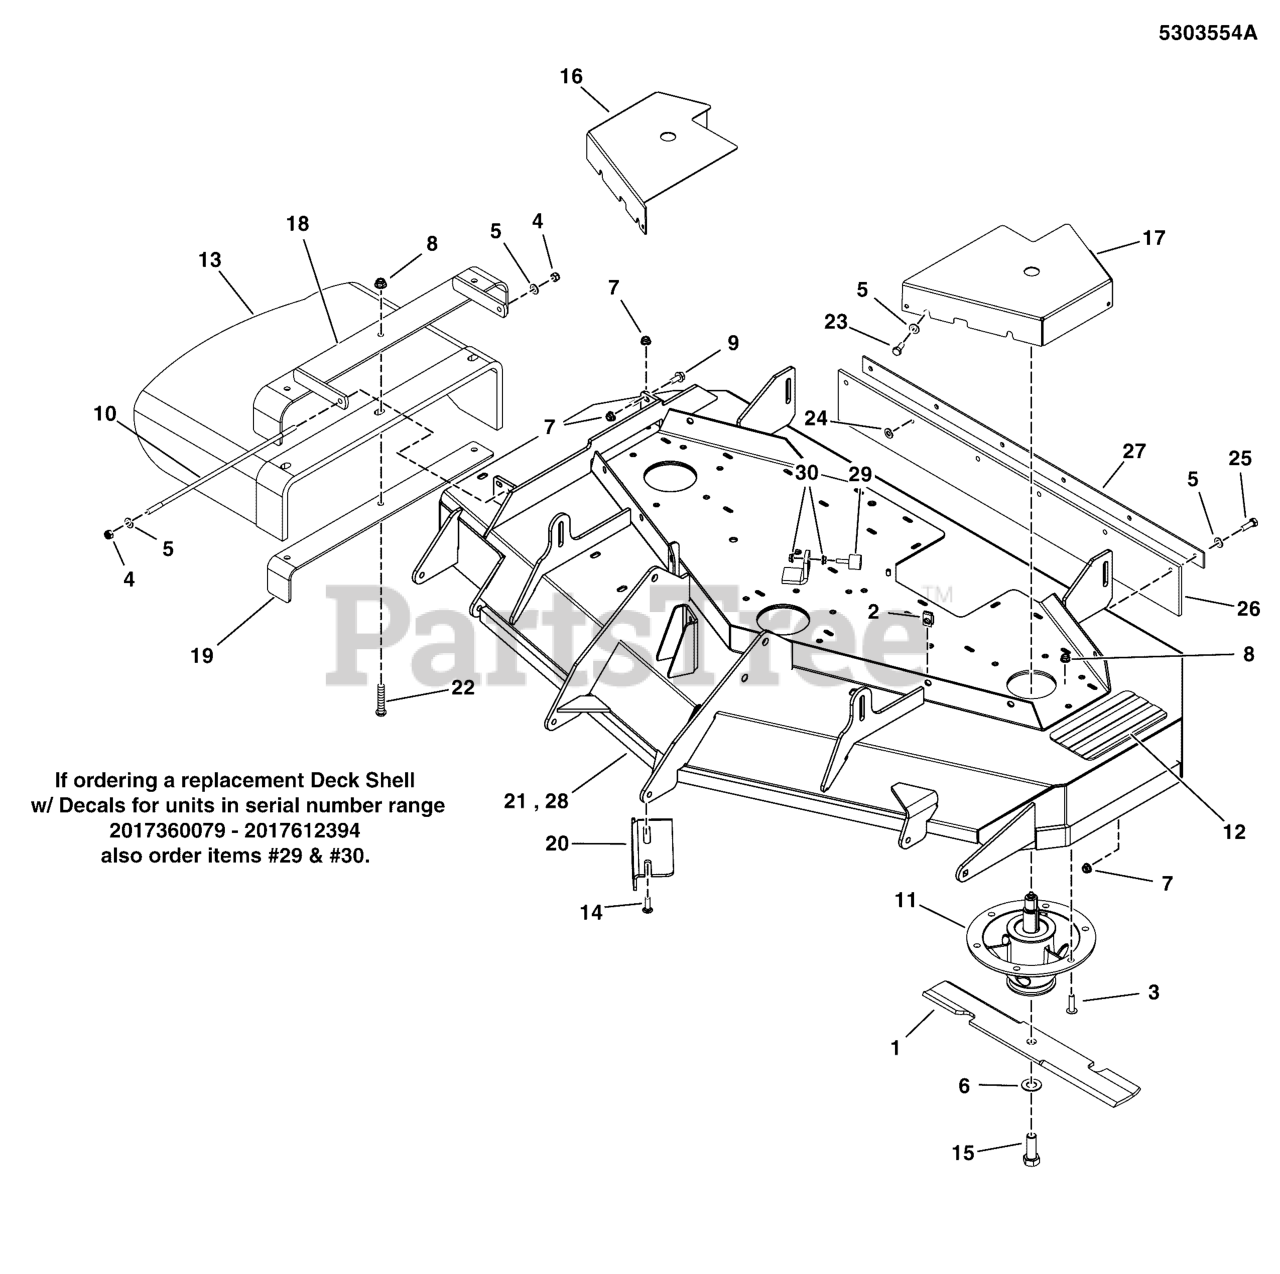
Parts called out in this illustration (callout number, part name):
1	BLADE, 18 X .25 X 2.5, 1 X 3.5 (SET OF THREE)
2	BODY CLIP, 5/16-18-7GA MATERIAL
3	BOLT, 3/8-16 X 1, FLANGE, GD 5, CZ
4	NUT, 5/16-24 HEX NYLON LOCK
5	WASHER, 5/16" SAE
6	WASHER, BLADE BOLT, 9/16" F436, CZ
7	NUT, 5/16-18 HEX NYLOCK FLANGE NUT
8	NUT, 3/8 - 16 HEX NYLOCK FLANGE
9	BOLT, 5/16-18 X 3/4 GD5
10	ROD, MOUNT, CHUTE, 61, CZ
11	SPINDLE ASSM, CAST IRON 8.0 - 6-BOLT
12	SAFETY WALK, 4.00 X 7.50
13	CHUTE, RUBBER DISCHARGE (5104442)
14	BOLT, 5/16-18 X 3/4, CARRIAGE, GD5, CZ
15	BOLT, 5/8-11 X 1-3/4 GD8
16	PLATE, DECK GUARD, RH - RED
17	PLATE, DECK GUARD, LH - RED
18	WELD, MOUNT, DISCHARGE CHUTE - BLK
19	SUPPORT, DISCHARGE CHUTE - BLK
20	PLATE, DEFLECTOR, 52 DECK - BLK
21	DECK SHELL W/ DECALS, 52, S150XT-DOM (5413377D)
22	BOLT, 3/8-16 X 1-1/2, CARRIAGE, GD5, CZ
23	BOLT, 5/16-18 X 3/4 GD5
24	5/16" PUSH-ON NUT RETAINER, STL, CZ
25	BOLT, 5/16-18 X 1" GRD5 YZ
26	FLAP, STRIPER, 61" DECK, IS3100, S200X
27	PLATE, SUPPORT - BLKV
28	DECK SHELL W/DECALS,52,S150XT,5414847D
29	BUMPER, RUBBER, 1/4-20 X 7/8" STUD
30	NUT, 1/4-20 HEX SERR. FLANGE
